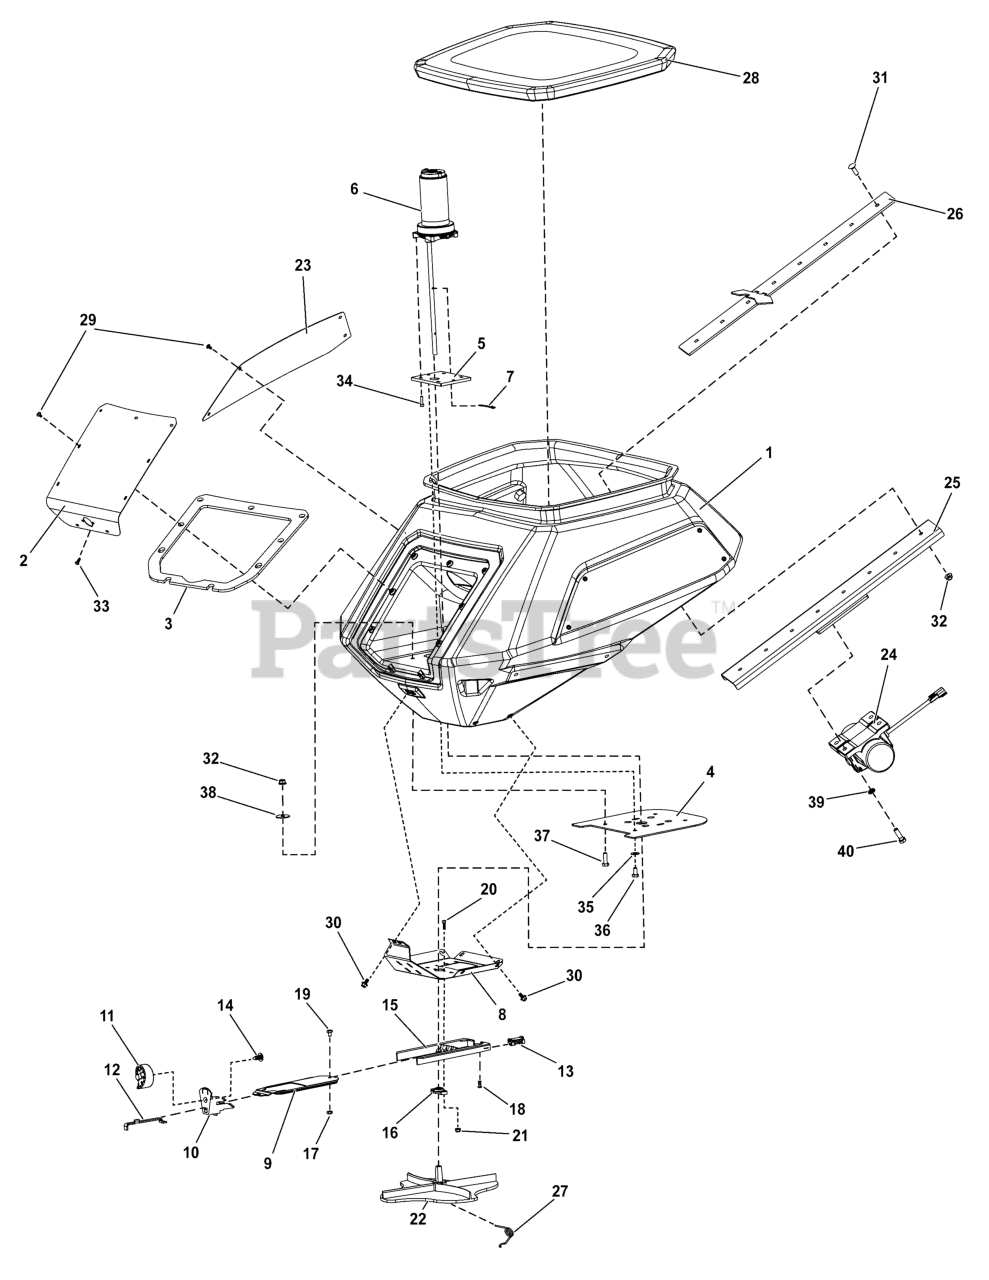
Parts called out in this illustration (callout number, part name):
1	HOPPER, GRANULAR 250 LBS
2	SHROUD, MOTOR HOPPER
3	GASKET, MOTOR HOPPER
4	PLATE, SCREEN SUPPORT CENTER
5	BRACKET, GEARMOTOR, SUPPORT
6	GEARMOTOR, SPINNER PLATTER
7	CLIP, SPINNER AGITATOR
8	BRACKET, HOPPER BOTTOM
9	PLATE, RATE GATE OFFSET
10	MOUNT, SPREADER DIAL
11	DIAL, CONTROLLER
12	PLATE, STOPPER, GATE OPENING
13	GUIDE, RATE GATE & DIFFUSER
14	PINE TREE CLIP, SPREADER FOR DIA .33"
15	BAFFLE, SPREADER DIFFUSER
16	BEARING, FLANGE IGUS EFOI-6
17	NUT-HEX-NYLK, .250"-20 TH SS188
18	FITTING, SWIVEL ACCUWAY
19	SCR-CAP, HEX .250"-20 X .375" SS188 SPC
20	SCR-CAP, SH #10-24 X .625" SS188
21	NUT-HEX-NYLK, FLG .#10-24 SS188
22	PLATE, SPREADER SPINNER
23	PLATE, BRANDING HOPPER
24	VIBRATOR, Z80 12VDC
25	WELD, VIBRATOR MOUNT
26	WELD, SCREEN SUPPORT
27	CLIP, SPREADER SPINNER
28	COVER, HOPPER FS5250 VOYAGER
29	SCR-CAP, SBWH #10-24 X .375" SS188
30	SCR-CAP, HSWH .250"-20 X .500" SS188
31	BLT-RDHDSQNK, .3125"-18 X 1.000" SS188
32	NUT-HEX-NYLK, FLG .3125"-18 SS188
33	SCR-TAP, PLPH 10-14X.500" TR 48-2 SS188
34	SCR-CAP SH, #10-32 X .750" SS188
35	WSHR-STL, FLT .343" X .750" X .050" SPC SS188
36	SCR-CAP, HEX .3125"-18 X .625" SS188
37	SCR-CAP, HEX .3125"-18 X 1.000" SS188
38	WSHR-SS, FLT .348"X1.250"X.065" FEN
39	WSHR-NORD LOCK 0.406" X 0.654" ZP
40	SCR-CAP, HEX .375"-16 X 1.250" F593C
